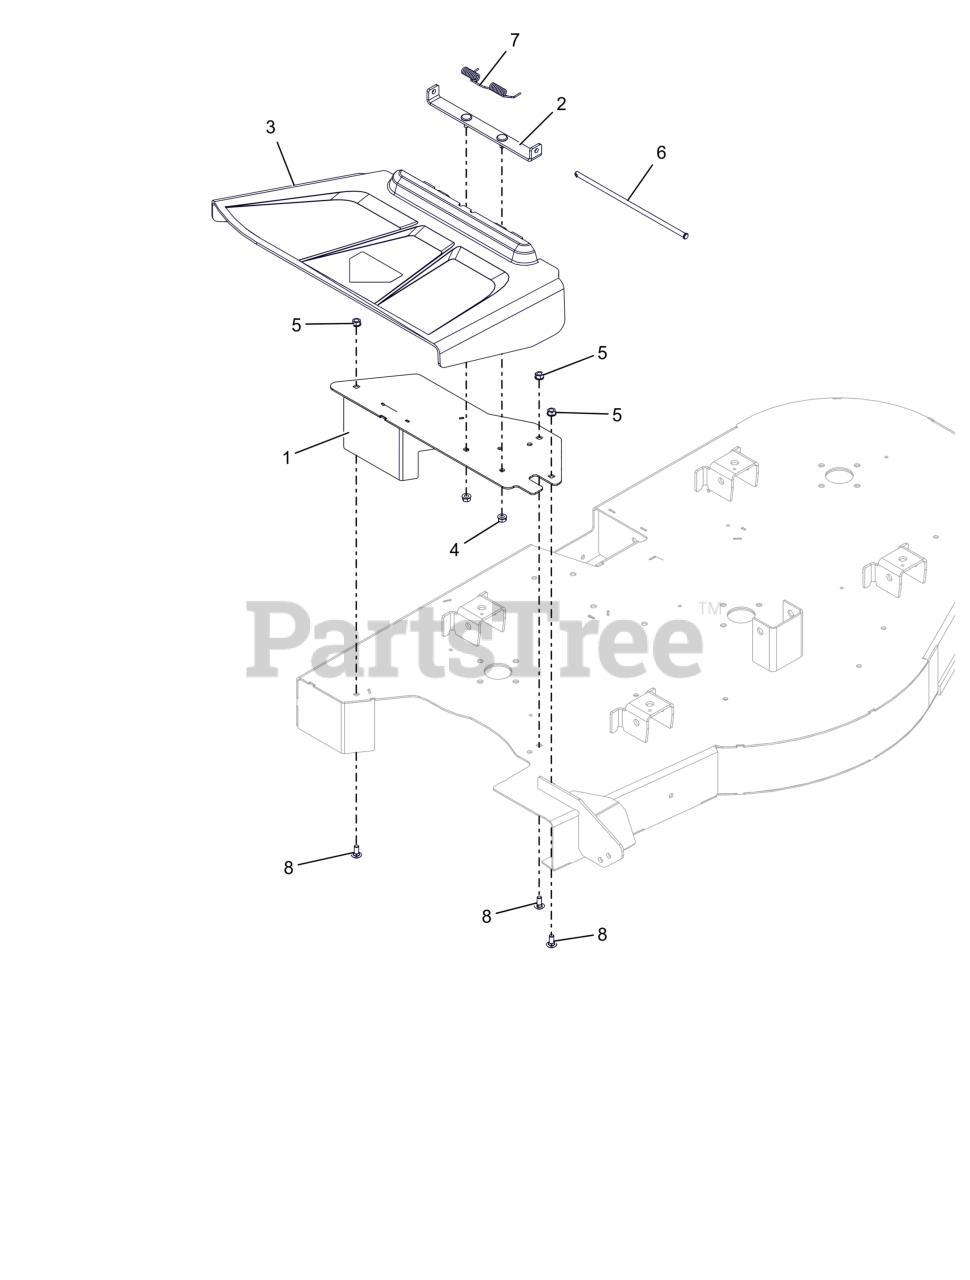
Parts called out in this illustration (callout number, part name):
1	WLDMT, DISCHARGE PLATE (ORANGE)
3	CHUTE, SIDE DISCHARGE
4	NUT-LK-TOP-FLG .312-18 GF ZCC
5	NUT,LK-CTR-FLG .31-18 GF ZCC
6	PIN, SLIC-.312X10.45
7	SPRING-TORSION
8	BLT,RHSN .31-18X.75 G5 ZCC
